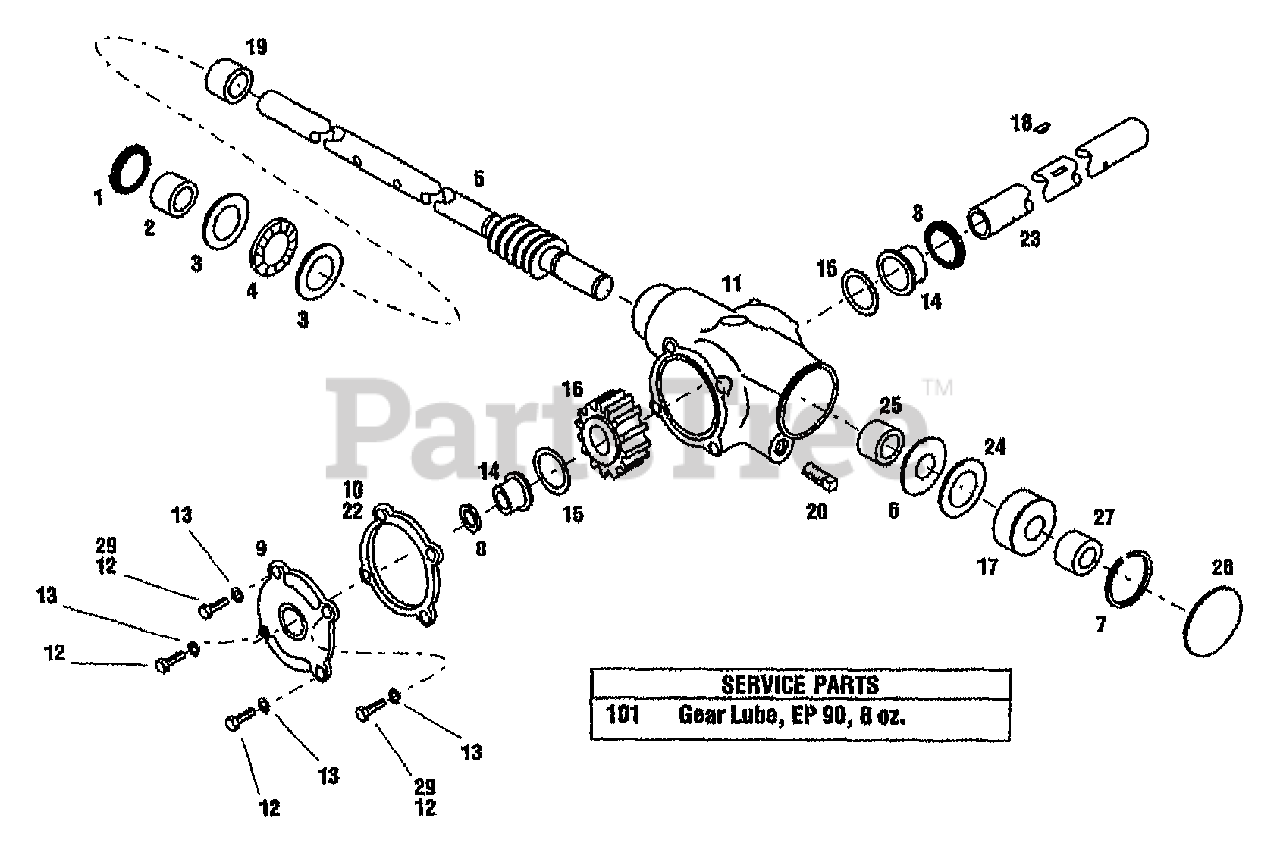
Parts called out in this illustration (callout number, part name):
1	SEAL-OIL 3/4 DIAMETER
2	BEARING-NEEDLE
3	RACE-THRUST
4	BEARING-THRUST
5	SHAFT-IMPELLER
6	WASHER
7	RING-RETAINING INTERNAL
8	SEAL-OIL
9	COVER-FLANGED
10	GASKET-COVER
11	CASE ONLY-GEAR
12	SCR-HH 1/4-20X.625 G5 ZP
13	WASHER-LK .25 ZP
14	BUSHING-FLANGE
15	RACE-THRUST
16	GEAR-WORM 20 TEETH
17	SPACER-1.503X.749X.56
18	KEY-WOODRUFF .25X.875
19	SPACER-1.0X.752X.302
20	PLUG-SQ HEAD 1/4-18 NPT
22	GASKET COMPOUND
23	SHAFT-AUGER
24	RACE-THRUST
25	SPACER-.812X.566X.448
26	PLUG-EXPANSION
27	BEARING-NEEDLE
29	LOCTITE-242 (.5 ML TUBE)
101	GREASE-LUBRICANT 55GAL
